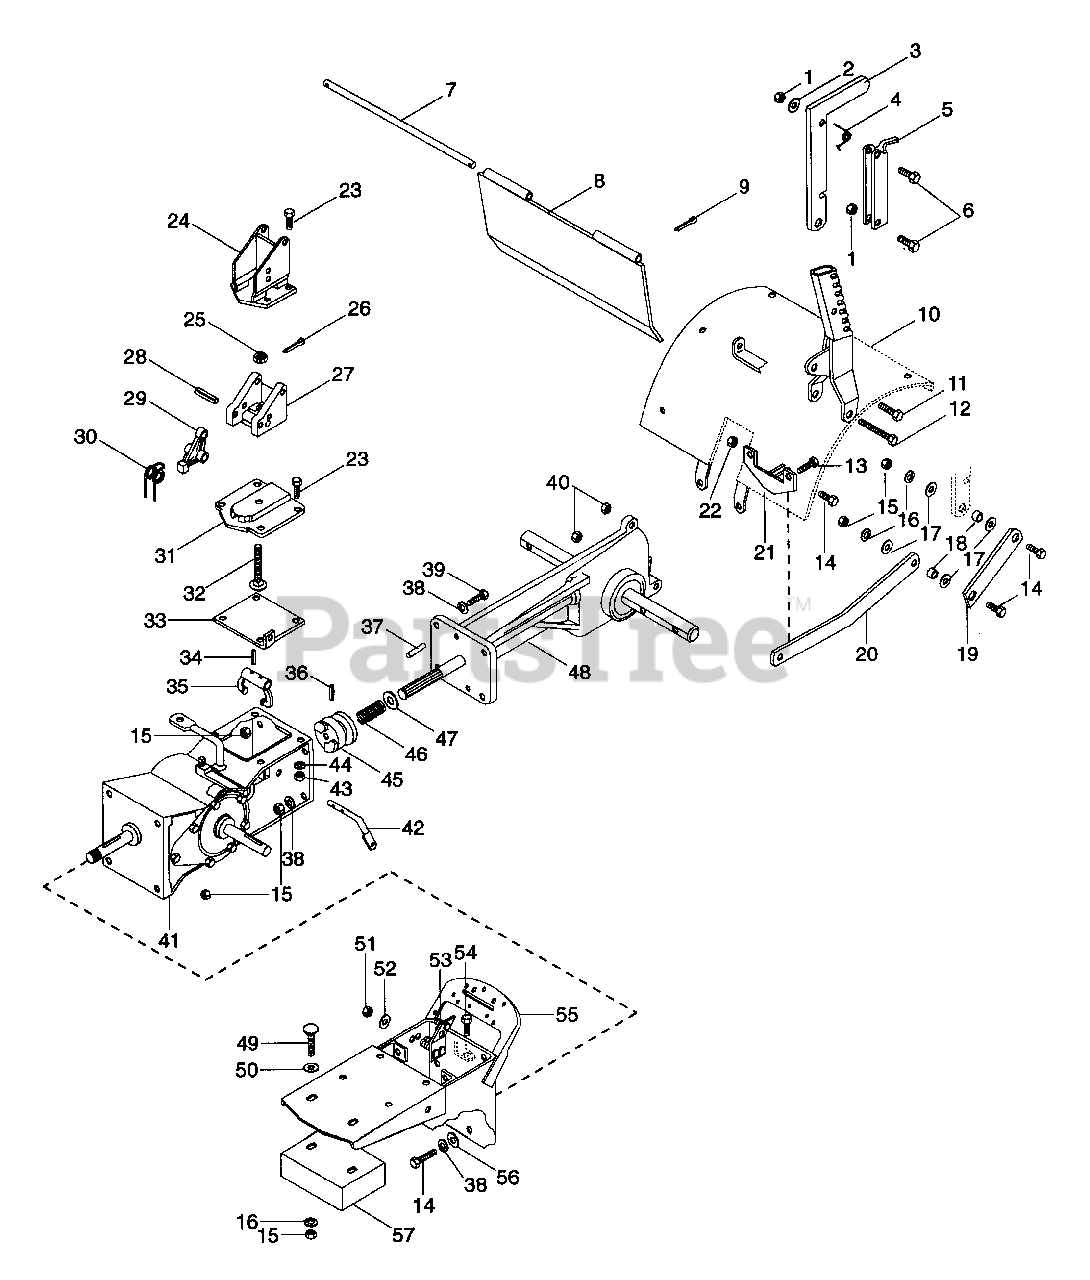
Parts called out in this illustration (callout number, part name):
1	NUT-LK-CTR .250-20 PL
2	WSHR-FL-STL.281X.62X.065 PL
3	HANDLE WELDMENT
4	SG-TORS .050X.25X2.33
5	TRIGGER
6	BLT-HEX .25-20X1.25 PL GR5
7	TAILBOARD PIN
8	TAILBOARD WELDMENT
9	PIN COTR .09X.50 PL
10	TINE HOOD W/DECAL
11	BLT-HEX .31-18X1.25 PL GR2
12	BLT-HEX .31-18X3.50 PL GR2
13	BLT-HEX .38-16X2.25 PL GR2
14	BLT-HEX .38-16X1.25 PL GR 2
15	NUT-HEX .375-16
16	WSHR-LK .375X.094 MED PL
17	WSHR-FL-STL .382X.812X.062
18	SPACER BUSHING .63 X .38 X .27
19	CHISEL POINT
20	DRAG LINK
21	PIVOT BRACKET
22	NUT-LK-CTR .375-16 GR A PL
23	BLT-HEX .31-18X1.00 PL GR 2
23	BLT-HEX .31-18X1.25 PL GR2
24	HANDLEBAR MOUNT
25	NUT-SL .50-13
26	PIN-COTR .12X1.0 PL
27	HANDLEBAR BRACKET
28	PIN-ROLL .313X2.00
29	LATCH
30	SG-TORS .109X.88X2.25
31	PIVOT CAP
32	SWIVEL BOLT
33	PIVOT BRACKET
34	PIN-ROLL .188X1.00
35	CLUTCH FORK
36	PIN-ROLL .125X1.00
37	PIN-GRV .375X1.00 TP C
38	WSHR-LK .438X.133 HVY
39	BLT-HEX .38-16X1.75 PL GR2
40	NUT-LK .312-18 GR A PL
41	TRANSMISSION GEARCASE ASSY
42	TINE ENGAGING FORK SHAFT
43	NUT-HEX .312-18
44	NUT-LK .312-18 GR A PL
45	TILLER JAW CLUTCH
46	SG-COMP .080X.97X2.18 WLD14
47	WSHR-FL-STL .755X1.375X.125
48	TILLER GEAR CASE - C.I.
49	BLT-RDHDSQNK .38-16X3.25 PL
49	BLT-RDHDSQNK .38-16X1.50 PL
49	BLT-RDHDSQNK .38-16X1.75 PL
49	BLT-RDHDSQNK .38-16X2.00 SHTYW
50	WSHR-FL-STL .630X1.005X.062 PL
51	NUT-LK .312-18 GR A PL
52	WSHR-FL-STL .323X.625X.062 PL
53	BELT FINGER BRACKET
54	SCR-TAP .312-18X.75 HWH PL TR
55	FRAME
56	WSHR-FL-STL.406X.812X.065PL
57	WEIGHT WAFER
